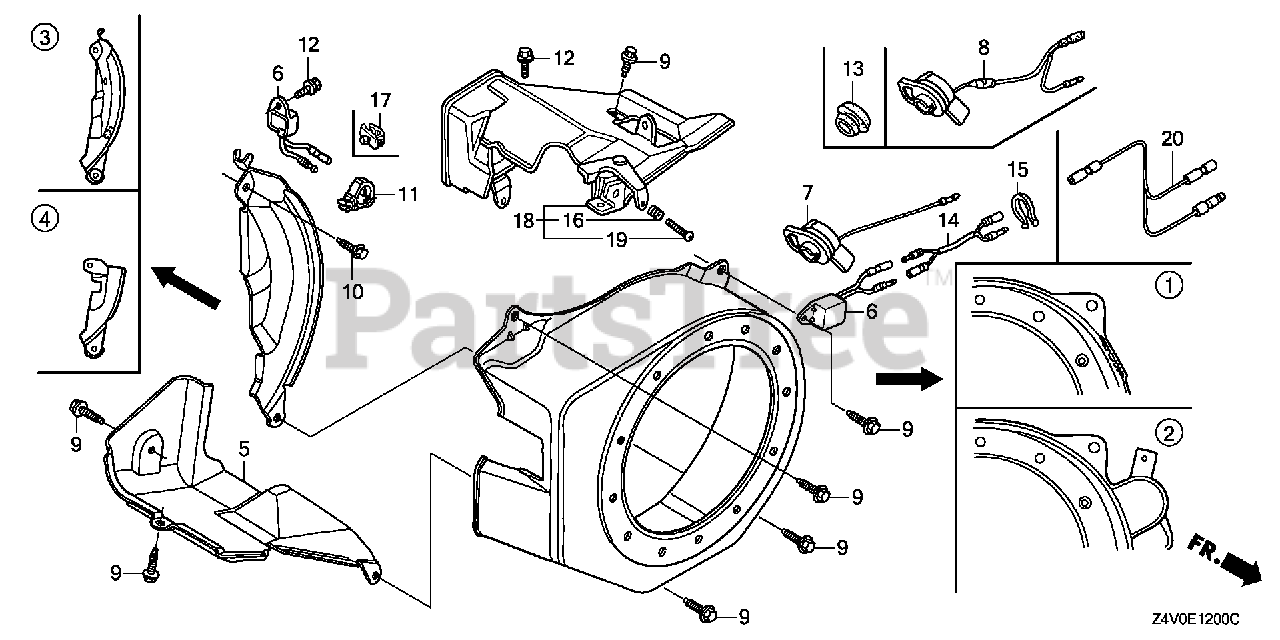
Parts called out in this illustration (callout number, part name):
1	COVER, FAN *NH1* (BLACK)
1	COVER, FAN *R280* (POWER RED)
3	PLATE, SIDE (OIL ALERT)
6	ALERT UNIT, OIL
8	SWITCH ASSY., ENGINE STOP (TOYO DENSO)
8	SWITCH ASSY., ENGINE STOP
9	BOLT, FLANGE (6X12) (CT200)
10	BOLT, FLANGE (6X20) (CT200)
11	CLIP, HARNESS
12	BOLT, FLANGE (6X8)
